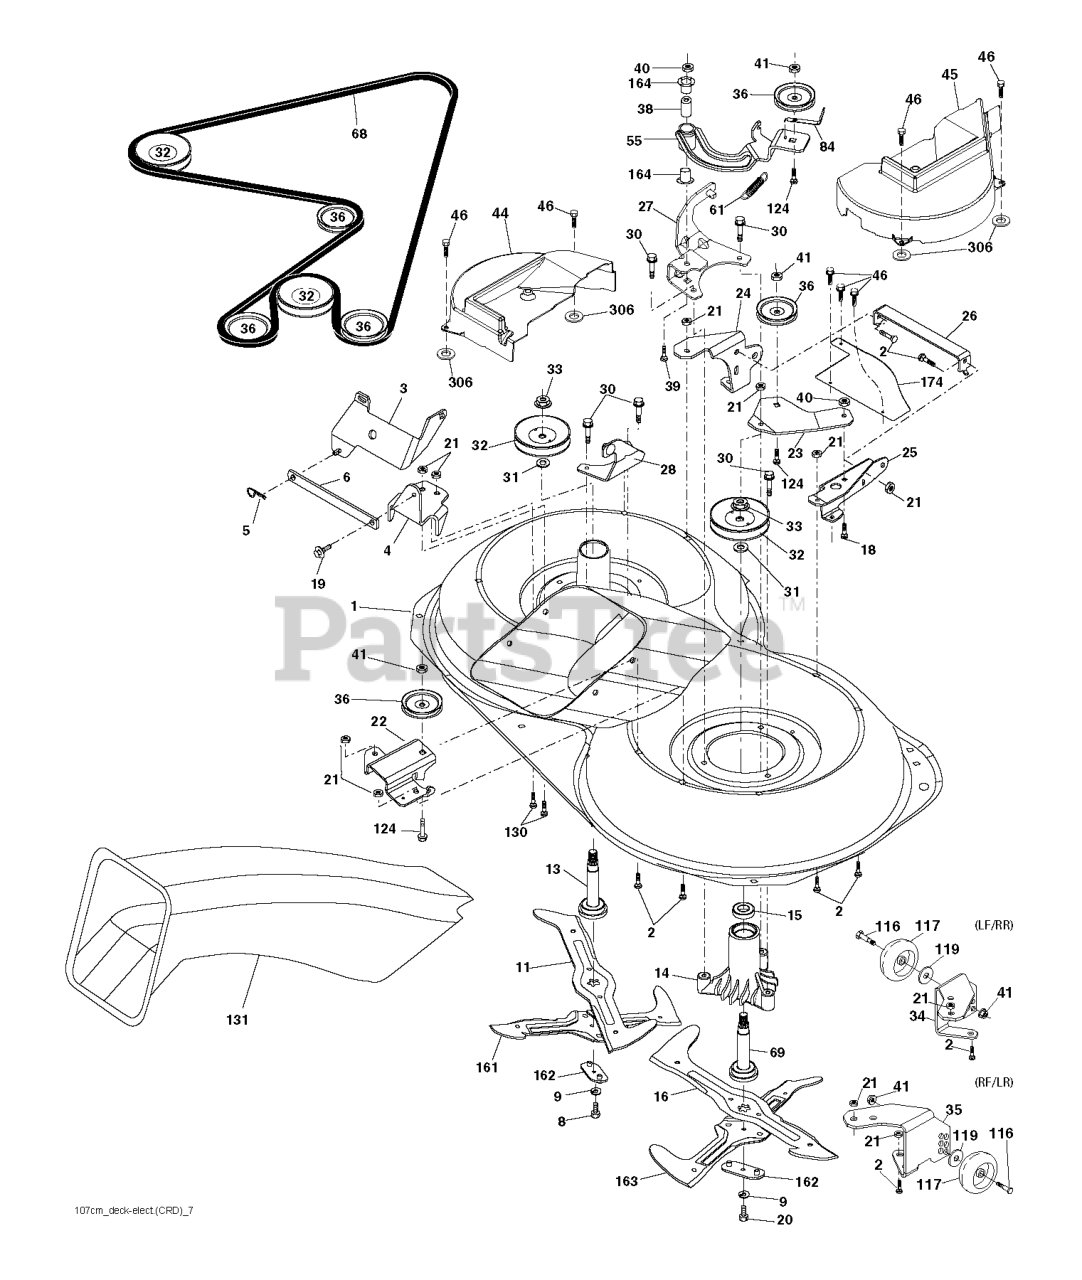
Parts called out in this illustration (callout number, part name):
1	Housing Asm. Mower 107 CRD
2	RP BOLT 5/16-18 X3/4 ZN/YEL GR
5	RETAINER-SPRNG RB
6	BAR.SWAY.92.CRD
8	BOLT.3/8-24X1.25 GR8
9	LOCKWASHER
11	BLADE.3N1.LH.CRD
13	SHAFT ASM VENT
14	HOUSING.MANDREL.VENTED (MACHD)
16	BLADE.3N1.RH.CRD
19	BOLT SHD 5/16-18
20	BOLT.3/8-24X1.25GR8. LHTHRD
21	LOCKNUT
22	BRACKET.IDLER.RR.107.CRD
24	BRACKET
25	BRACKET RF
26	SUPPORT
28	BRACKET
30	SCREW, WASHER HEAD
31	WASHER.SPACER.MANDREL
32	PULLEY.MANDREL.4.80 PD.2006
33	NUT.FLANGE.LOCK.TOP
34	BRACKET
35	BRACKET
36	PULLEY.IDLER.4.25
41	NUT LOCK FLG 3/8-16 UNC
46	SCREW.1/4-20X5/8
55	ARM.IDLER.107.CRD
61	SPRING
68	HEX-BELT 107 MOWER
69	SHAFT.ASM.W/LWR.BRG.RH.THREAD
84	KEEPER, BELT IDLER
116	BOLT.SHOULDER.3/8-16X3-5/8.
117	RP WHEEL. GUAGE RALLY
118	NUT LOCK FLG 3/8-16 UNC
119	WASHER
124	BOLT.3/8-16X1.50
130	BOLT.CARR.SQNK.5/16-18UNC.X3/4
131	CHUTE BAGGER
163	BLADE.CROSS.RH.CRD.107
164	BRNG T
174	PLATE
306	PALNUT 1/4
